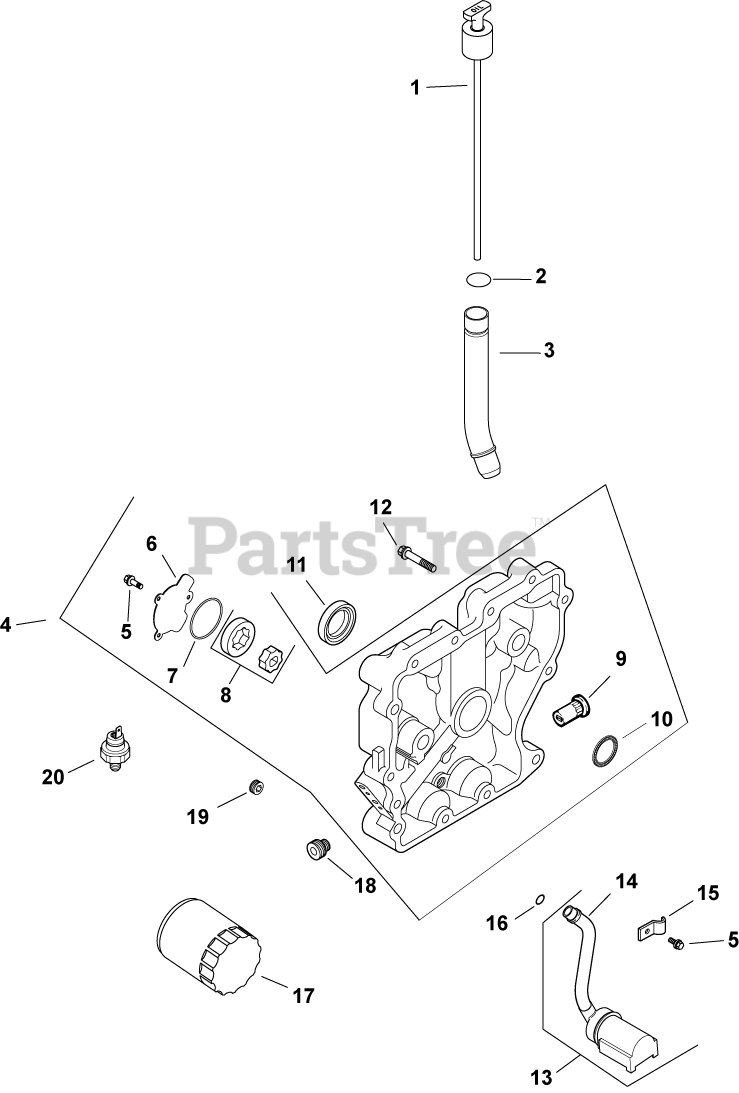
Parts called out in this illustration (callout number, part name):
3	TUBE, OIL FILL - DISCONTINUED
4	PLATE, CLOSURE & BEARING
5	SCREW,FLG THD FRM M5X0.8X16-(#25086398S)
6	COVER, OIL PUMP
7	O-RING (1.78" DIA)
8	PUMP ASSEMBLY, OIL
9	VALVE, OIL PRESSURE RELIEF
10	BEARING, CRANKSHAFT
11	SEAL, OIL
12	SCREW, FLG M8X1.25X45
13	KIT, OIL PICK-UP
14	PICK-UP, OIL SCREEN
16	O-RING (.5" DIA)
17	OIL FILTER
18	NIPPLE, OIL FILTER
19	PLUG, CTSK PIPE 1/8"
20	SWITCH, PRESSURE - USE 24 099 03-S
